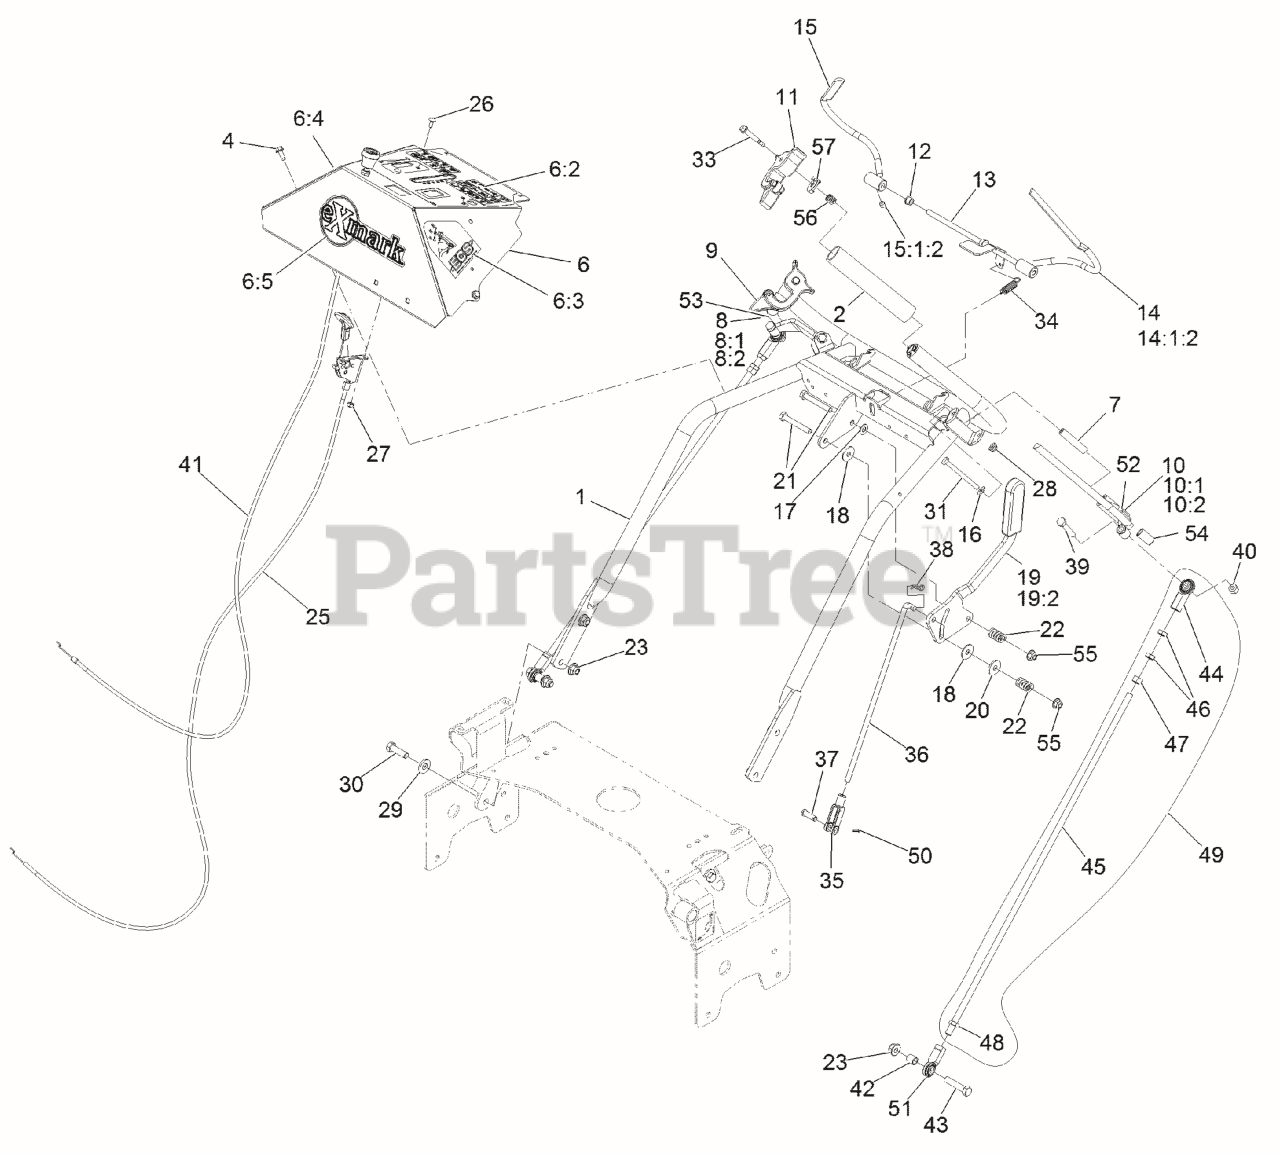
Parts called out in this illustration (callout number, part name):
1	WELD, HANDLE
2	GRIP-BAR, HANDLE
4	SCREW-HWH
6	ASM, CONSOLE W/ DECALS
7	BUSHING-LEVER, DRIVE
8	DRIVE LEVER-ASM, RH
8:1	WLD,RH DRIVE LEVER
8:2	BUSHING, SLEEVE
9	ASM,LATCH RH THUMB
10	DRIVE LEVER-ASM, LH
10:1	WLD,LH DRIVE LEVER
10:2	BUSHING, SLEEVE
11	ASM,LATCH LH THUMB
12	BUSHING-NYLON
13	WLD,OPC LEVER AXLE
14	WLD,LH OPC LEVER
14:1:2	SCREW-SET
15	WLD,RH OPC LEVER
15:1:2	SCREW-SET
16	WASHER-FLAT
17	WASHER-PLAIN
18	WASHER-FRICTION
19	LEVER, SHIFT W/GRIP
19:2	GRIP-HANDLE, STEERING
20	WASHER-FRICTION
21	SCREW-HH
22	SPRING-COMPRESSION
23	NUT-HF, NI
25	CONTROL-THROTTLE
26	BOLT-CARR
27	NUT-LOCK, NI
29	WASHER-BELLEVILLE
30	SCREW-HH
31	SCREW-HH
33	SCREW-SHOULDER
34	SPRING-EXTENSION
35	YOKE-ADJUSTABLE
36	ROD,SPEED CONTROL
37	PIN-CLEVIS
38	PIN-COTTER
39	SCREW-HH
40	NUT-LOCK, NI
41	CABLE, CHOKE
42	SPACER-TUBE, PUMP LINK
43	SCREW-HH
44	JOINT-BALL, END
45	LINK,DRIVE (PLTD)
46	NUT-HJ
47	NUT-HEX
48	NUT-HEX JAM, LH
49	DRIVE LINK ASM
50	PIN-COTTER
51	JOINT-BALL END, LH
52	WLD,LH DRIVE LEVER
53	WLD,RH DRIVE LEVER
54	BUSHING, SLEEVE
55	NUT-HF, NI
56	SPRING-TANK, FUEL
57	LATCH, ECS
